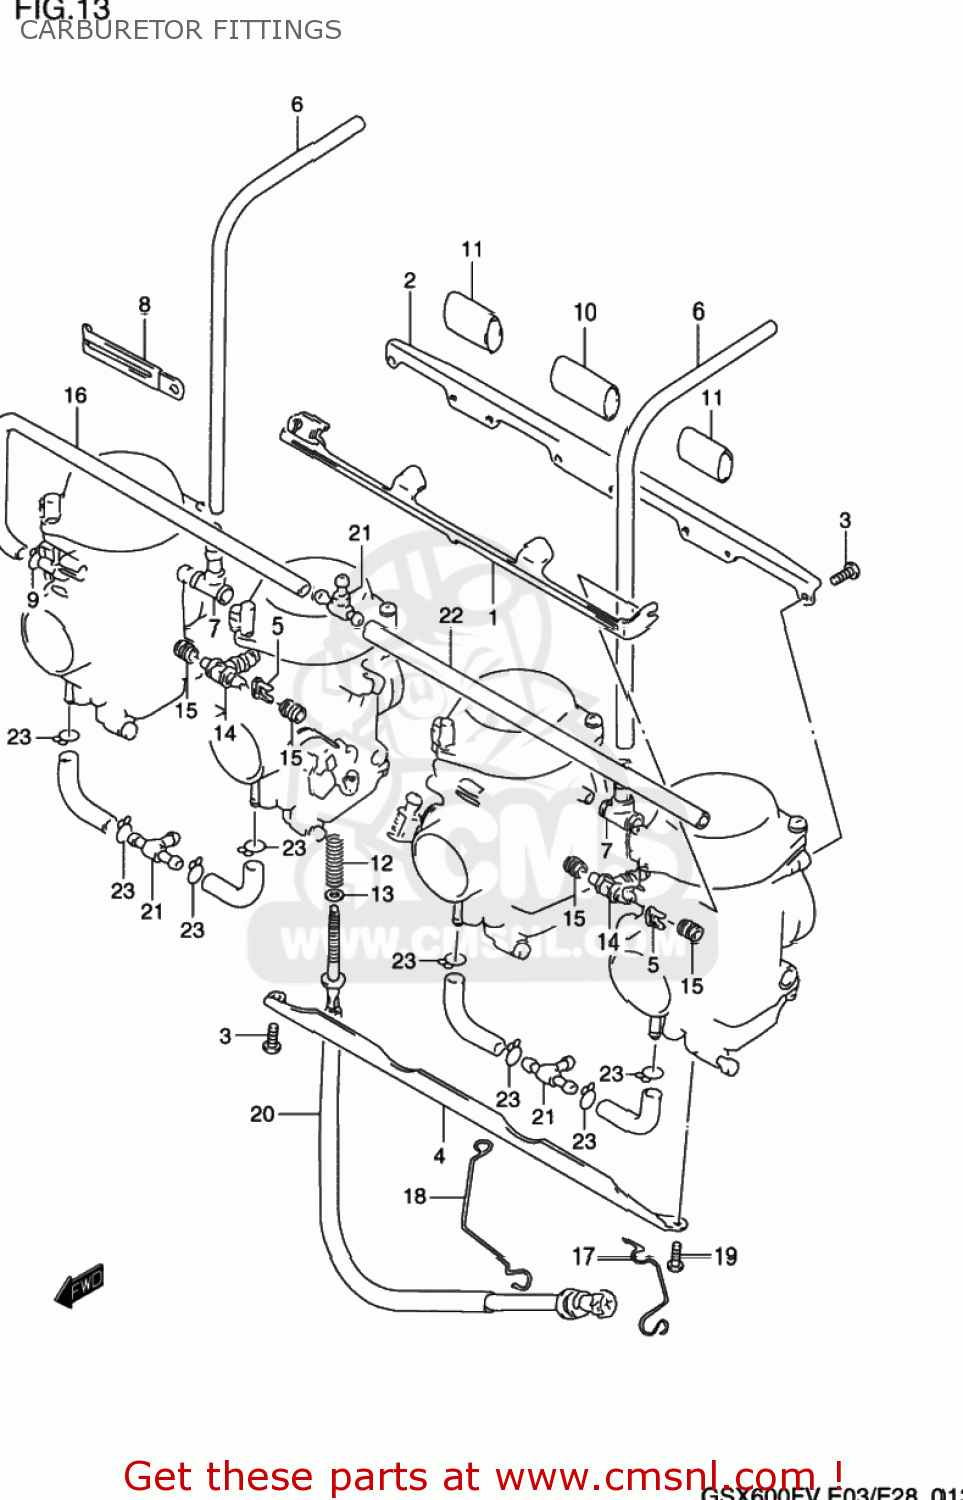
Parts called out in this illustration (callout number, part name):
1	LEVER
2	PLATE
3	SCREW
4	PLATE
5	HOLDER
6	HOSE(7X10.2X600)
7	HOSE
8	CLAMP(L:65)
9	CLIP
10	HOSE(16X19X100)
11	HOSE(16X19X100)
12	SPRING
13	WASHER
14	NIPPLE
15	SEAL
16	HOSE
17	CLIP
18	CLIP
19	SCREW
20	ADJUSTER
21	NIPPLE
22	HOSE(5X9X600)
23	CLIP
